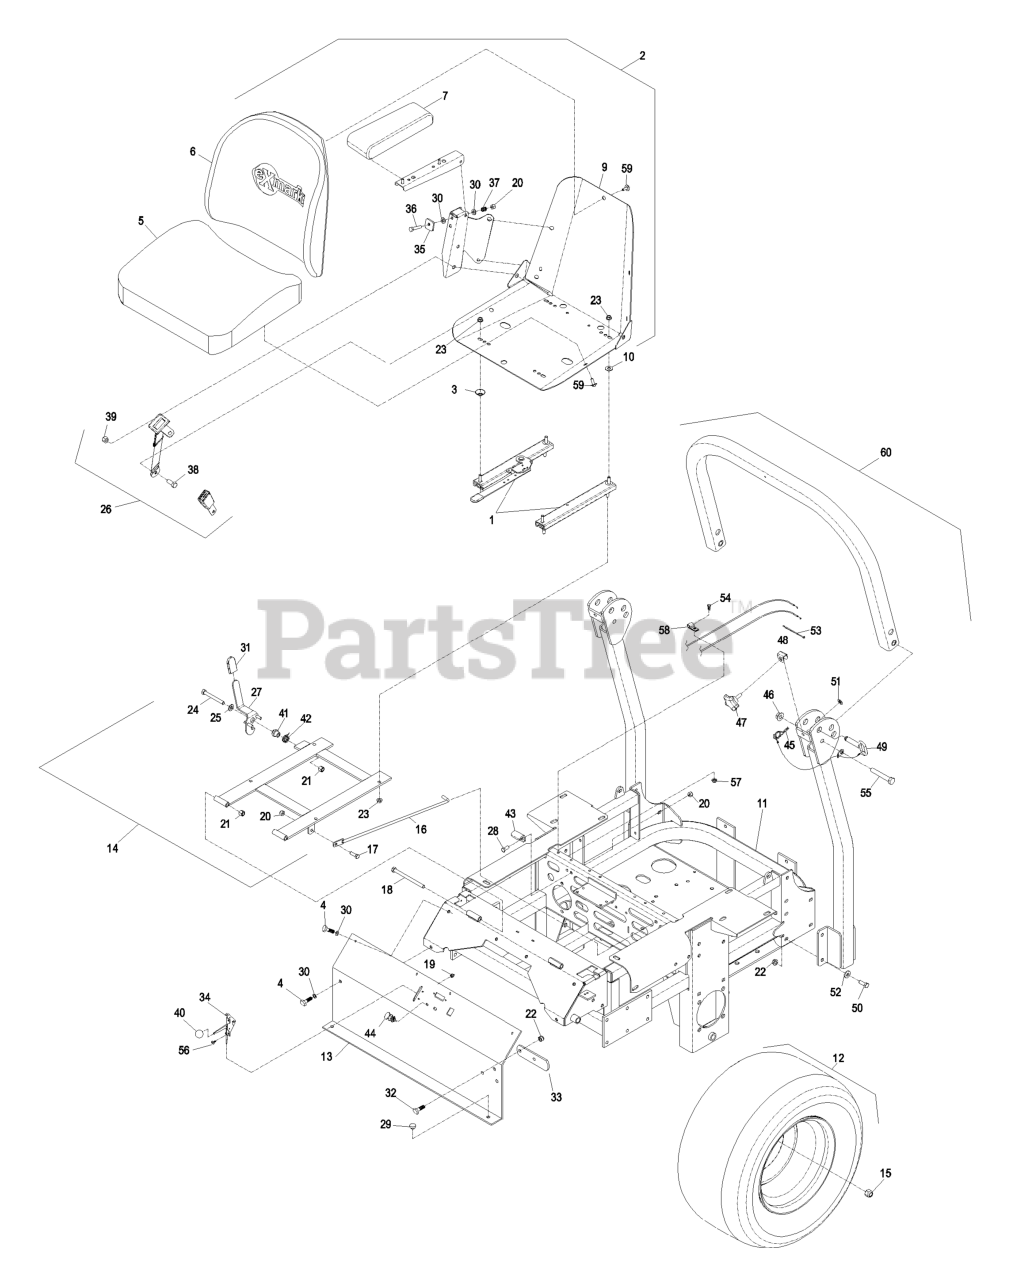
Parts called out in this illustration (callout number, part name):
1	TRACK-SEAT
2	KIT,SEAT W/ARMREST ADJ.
3	SPACER-TRACK
4	SCREW-HH
5	CUSHION,SEAT BOTTOM
6	CUSHION,SEAT BACK
7	CUSHION,ARMREST RH
9	FRAME-SEAT
10	WASHER-FLAT
11	KIT, LAZER MAINFRAME W/DE
14	ASM,SEAT FRAME
15	NUT-LUG
16	ROD-HOLDUP, SEAT
17	SCREW-HH
18	SCREW-HH
19	NUT-LOCK, NI
20	NUT-LOCK, NI
21	NUT-LOCK, NI
22	NUT-HHF, WHIZ
24	SCREW-HH
25	WASHER-FLAT
26	SEATBELT KIT
27	LATCH ASM
28	SCREW-HH
30	WASHER-PLAIN
31	GRIP-LEVER
32	SCREW-HH
33	STOP-BRAKE, PARK
34	THROTTLE CABLE ASM
35	TAB,ARMREST ADJUSTMENT
36	SCREW-HH
37	SPRING-TANK, FUEL
38	SCREW-HH
39	NUT-LOCK, NI
40	KNOB-BALL
41	BUSHING-LATCH, SEAT
42	SPRING-TORSION
43	CATCH-LATCH, SEAT
44	CONTROL-CHOKE
45	HAIRPIN
49	PIN-FOLD, ROPS
50	SCREW-HH
51	NUT-PUSH
52	WASHER-BELLEVILLE
53	SCREW-HH
54	TIE-PLASTIC
55	SCREW-HH
56	BOLT-CARR
58	CLIP-LOOM
59	BOLT-SEAT
60	KIT, ROPS LZ >510,000
